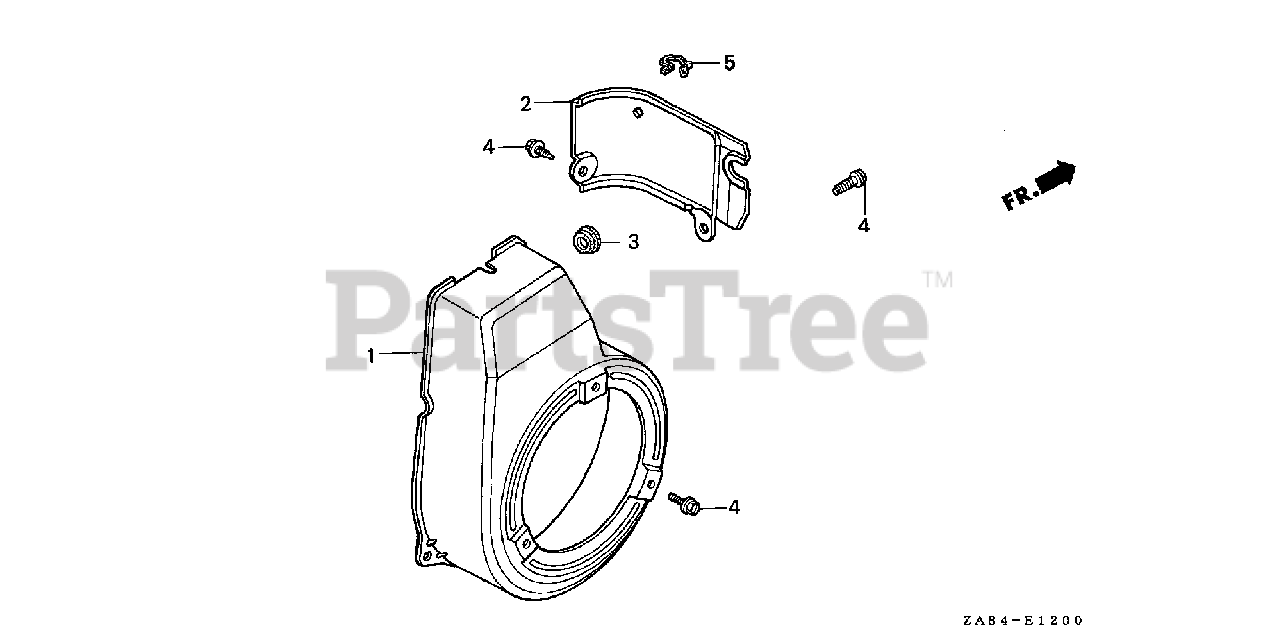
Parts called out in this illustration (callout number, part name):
1	COVER, FAN *R8* (BRIGHT RED)
3	GROMMET, DRAIN HOLE
4	BOLT, FLANGE (6X12) (CT200)
5	CLIP, TUBE (7MM)
